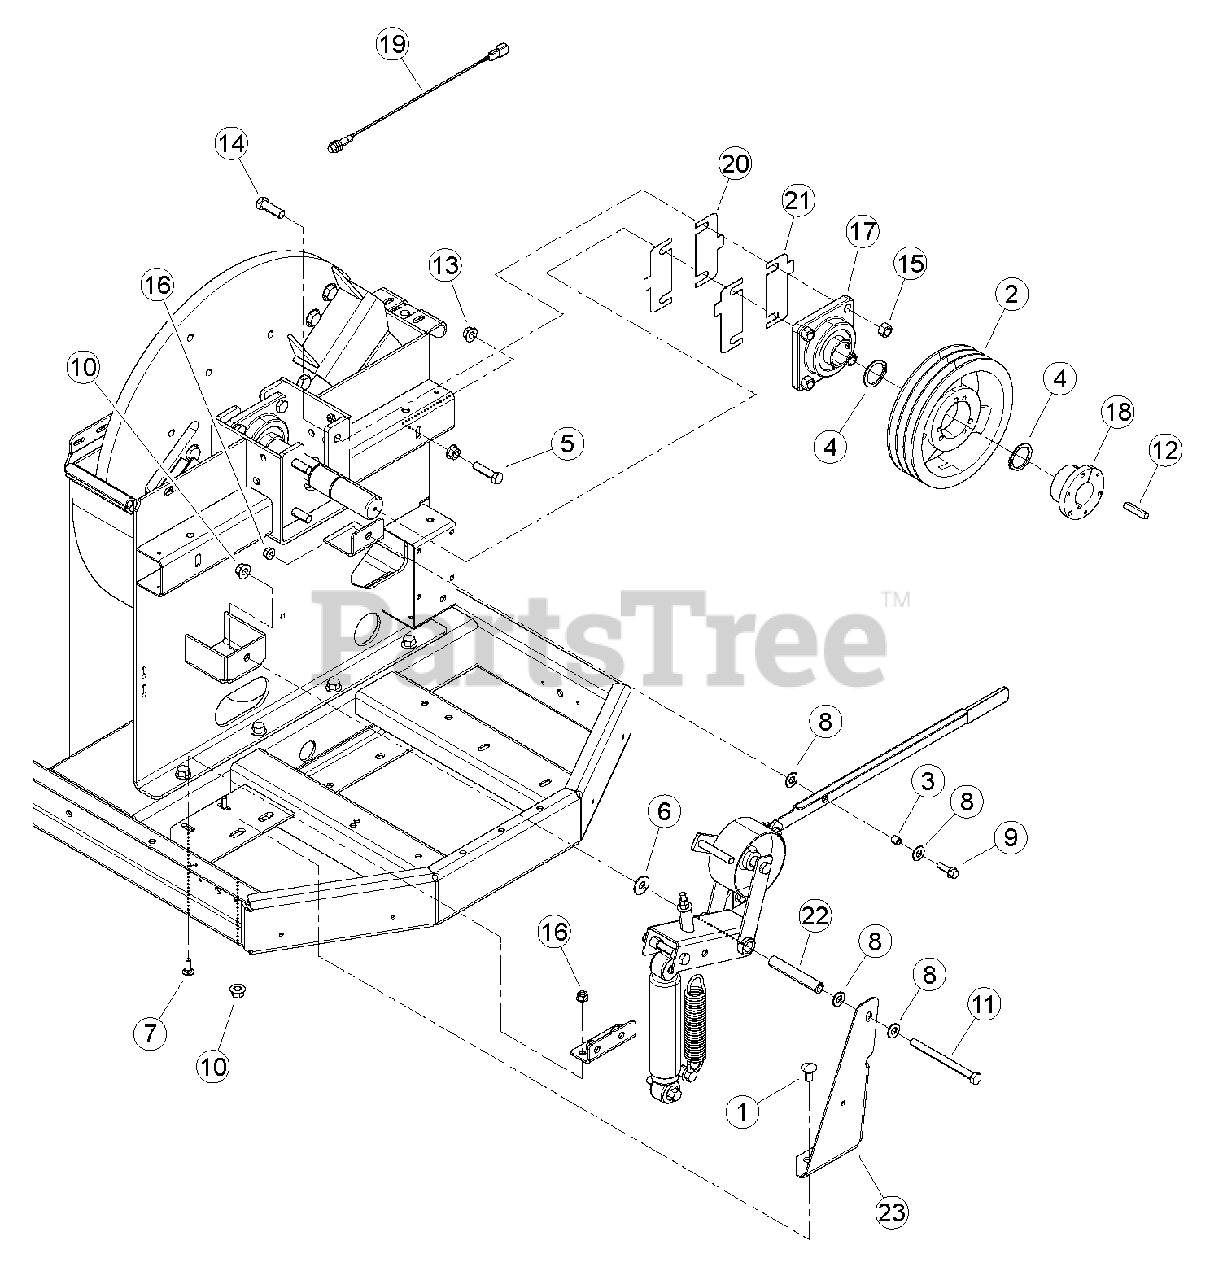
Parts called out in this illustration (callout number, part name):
1	BOLT, 1/2 X 1 GR5 CRG ZP
2	SHEAVE, 3BQ9.4, SK
3	BUSHING, 3/8 X 1/2 SLEEVE LUBE
4	RING, 1-3/4 EXT HEAVY DUTY SNAP
5	BOLT, 1/2-13 X 2 GR5 HEX CAPSCREW
6	WASHER, 1/2 FLAT
7	BOLT, 3/8-16 X 1 GR5 CRG
8	WASHER, 1/2 SAE FLAT
9	BOLT, 3/8 X 1-1/4 FLANGE NC
10	NUT, 1/2-13 NYLOCK FLANGE
11	BOLT, 1/2 X 6 G5 HCS - ZP
12	KEY, 3/8" SQ X 2" LG PLAIN
13	NUT, 1/2 SPIRAL LOCK NC ZP
14	BOLT, 9/16 X 1-3/4 HEX GR5 ZP
15	NUT, 9/16 CENTER LOCK GRB ZP
16	NUT, 3/8-16 NYLOCK FLANGE
17	BEARING, 1-3/4 4 BOLT FLANGE
18	BUSHING, SK 1-3/4"
19	SENSOR, M12 PNP PROXIMITY (REPLACEMENT PART)
20	SHIM, 20 GA.
21	SHIM, 16 GA.
22	BUSHING, IDLER PIVOT
23	BRACE, IDLER
